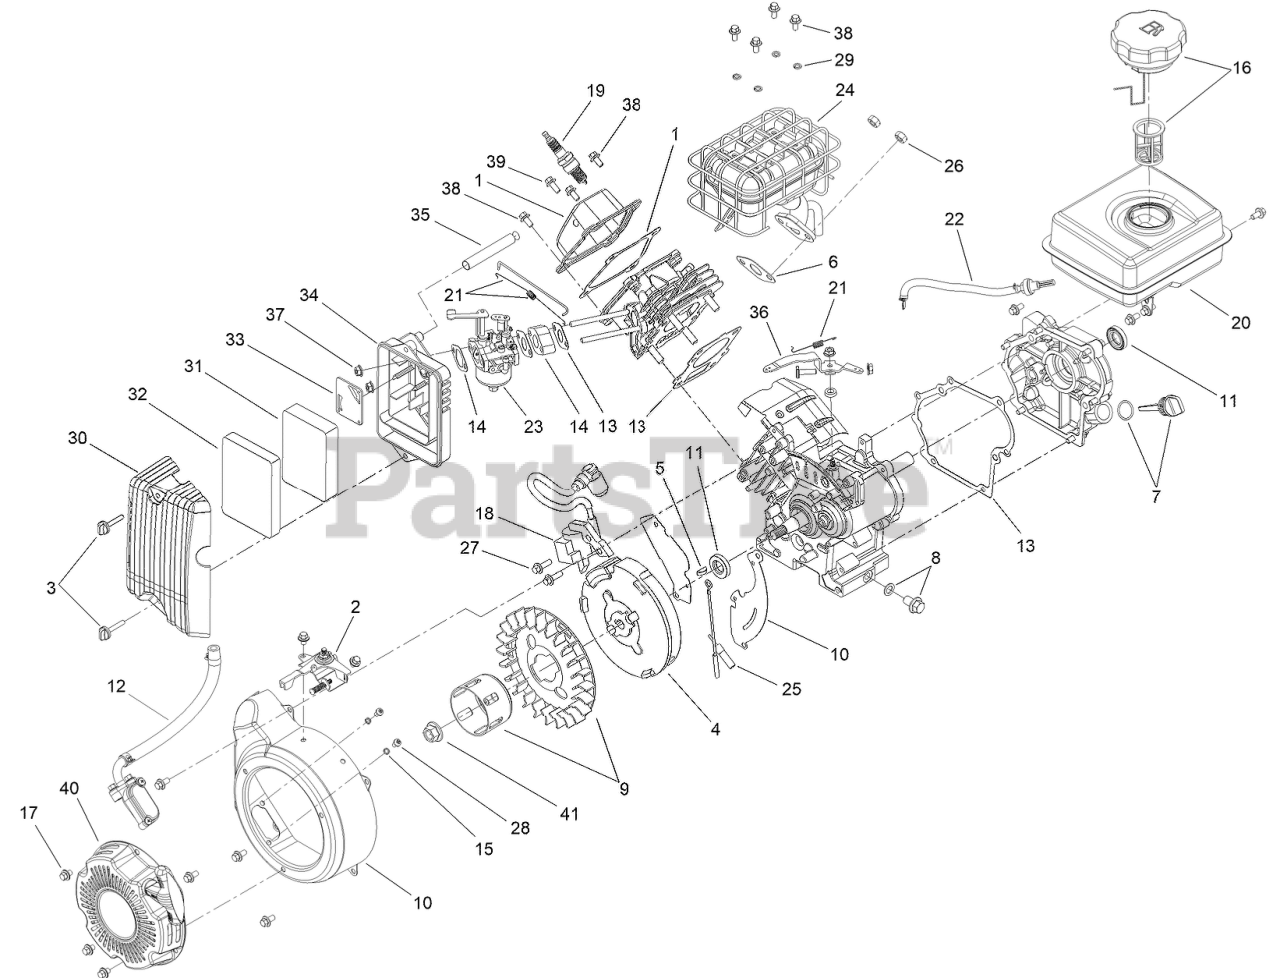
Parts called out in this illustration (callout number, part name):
1	VALVE COVER KIT
2	CONROL-THROTTLE
3	SCREW-TMBS
4	FLYWHEEL
5	KEY-WOODRUFF
6	GASKET-EXHAUST
7	DIPSTICK
8	PLUG-OIL
9	FAN KIT
10	BLOWER HOUSING KIT
11	SEAL-OIL
12	AUXILIARY INTAKE KIT
13	GASKETS-ENGINE
14	GASKETS-CARBURETOR
15	WASHER-LOCK
16	FUEL CAP KIT
17	SCREW-RHF
18	COIL-IGNITION
19	SPARK PLUG
20	FUEL TANK KIT
21	THROTTLE LINKAGE KIT
22	FUEL LINE KIT
23	CARBURETOR
24	MUFFLER
25	IGNITION KIT
26	NUT-HEX
27	SCREW-RHF
28	SCREW-PPHMS
29	WASHER-LOCK
30	COVER-AIR CLEANER
31	CAP-AIR FILTER
32	BASE-AIR FILTER
33	PLATE-AIR FILTER
34	BOX-AIR FILTER
35	TUBE-BREATHER
36	ARM-GOVERNOR
37	NUT-HEX
38	SCREW-RHF
39	SCREW-RHF
40	RECOIL
41	NUT-HEX
